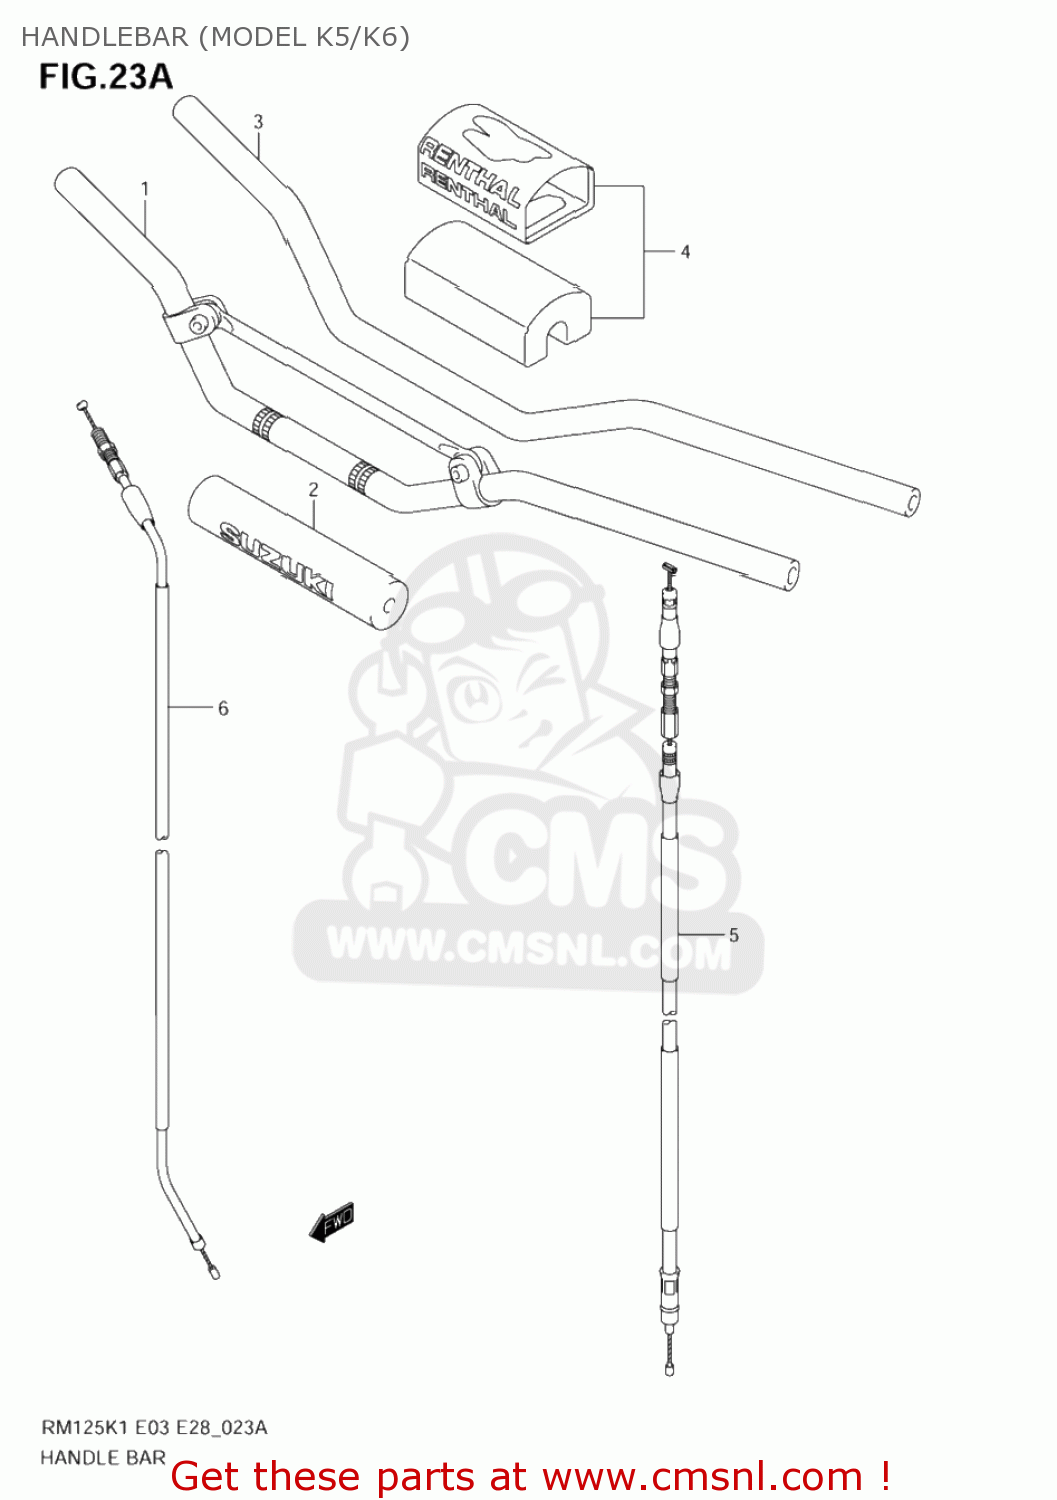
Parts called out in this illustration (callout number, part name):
1	HANDLEBAR
2	PAD SET,CROSS (NAS)
3	HANDLEBAR
4	PAD SET,HANDLEBAR (NAS)
5	CABLE ASSY,CLU
6	CABLE ASSY,THROTTLE
